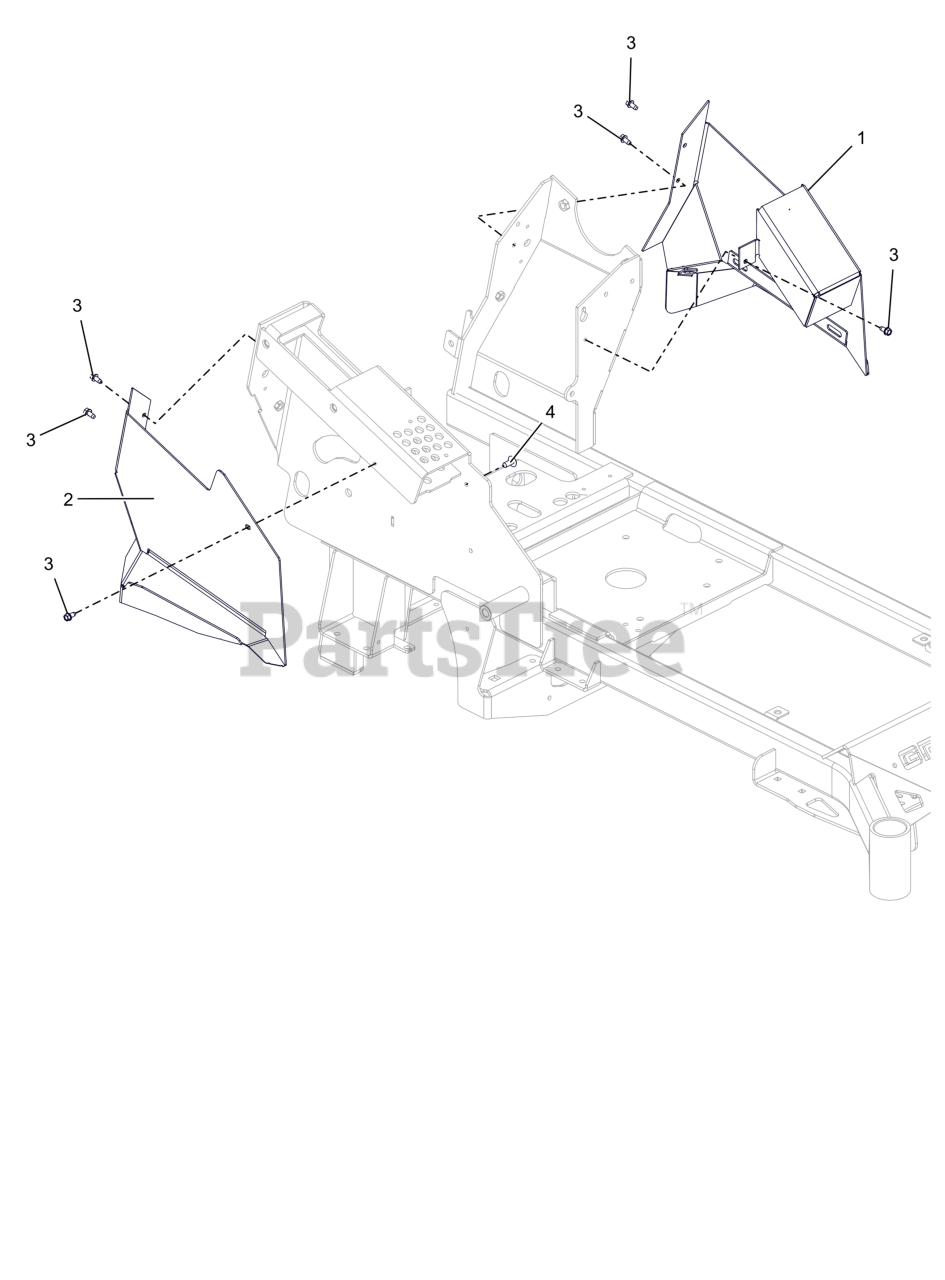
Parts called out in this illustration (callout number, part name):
1	WLDMT, LH FENDER (BLACK)
2	WLDMT, RH 32-36" FENDER (BLACK)
3	SCR-TAP .25-20X.50 HWH ZCC
4	XMAS TREE FASTNER-BLACK
